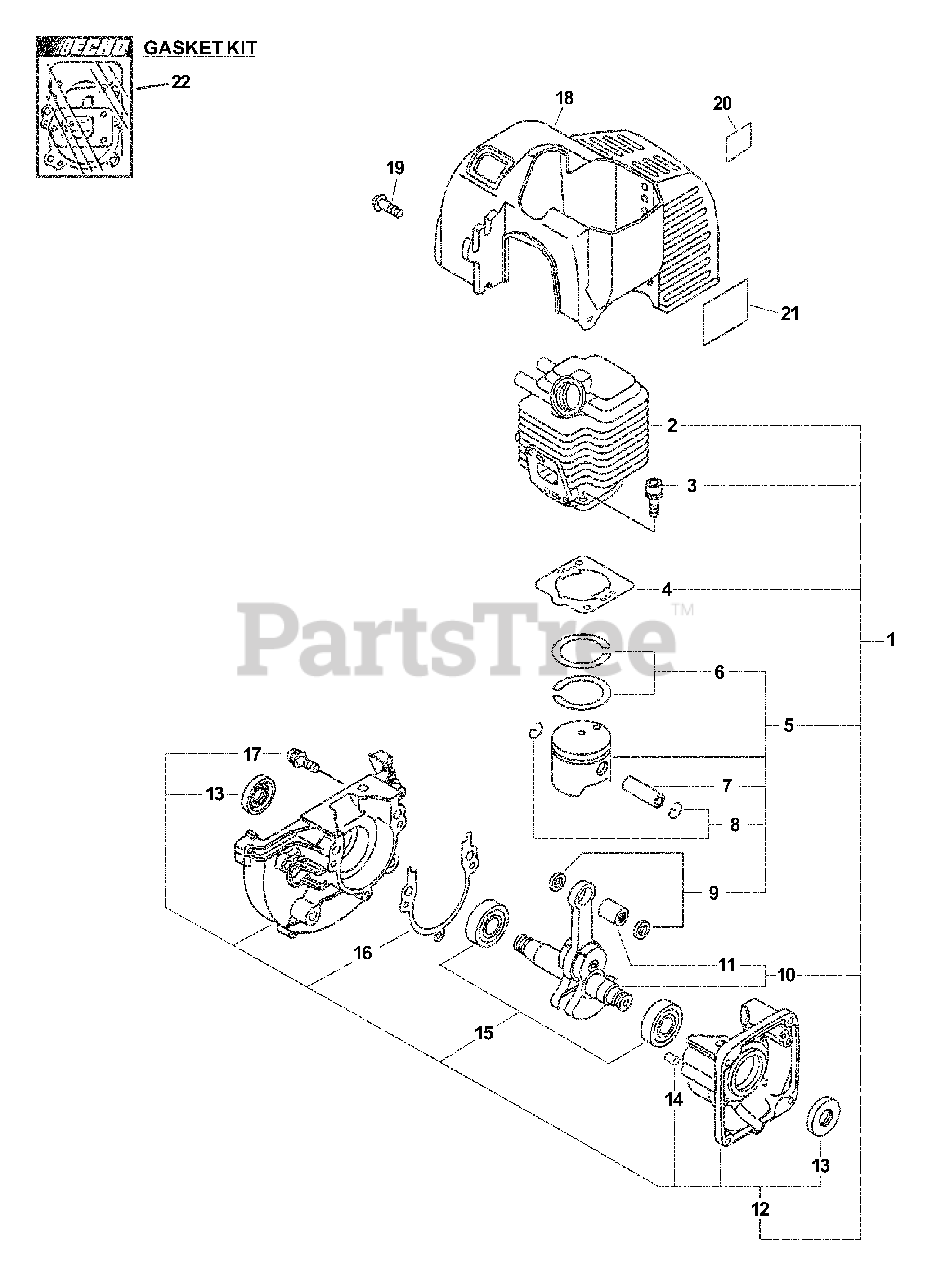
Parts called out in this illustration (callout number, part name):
1	SHORT BLOCK -- SB1065
2	CYLINDER
3	SCREW - 5X22
4	GASKET, CYLINDER
5	PISTON KIT
6	RING, PISTON
7	PIN, PISTON
8	RING, RETAINING
9	SPACER, PISTON
10	CRANKSHAFT ASSY
11	BEARING, NEEDLE - 8
12	CRANKCASE KIT
13	SEAL, OIL
14	PIN - LOCATING
15	BEARING, BALL - 6201
16	GASKET, CRANKCASE
17	SCREW - 5X28
18	COVER, ENGINE
19	SCREW - 4X12
20	LABEL - HOT SURFACE
21	LABEL - MODEL EDR-210
21	LABEL - MODEL ED-200
22	GASKET KIT
